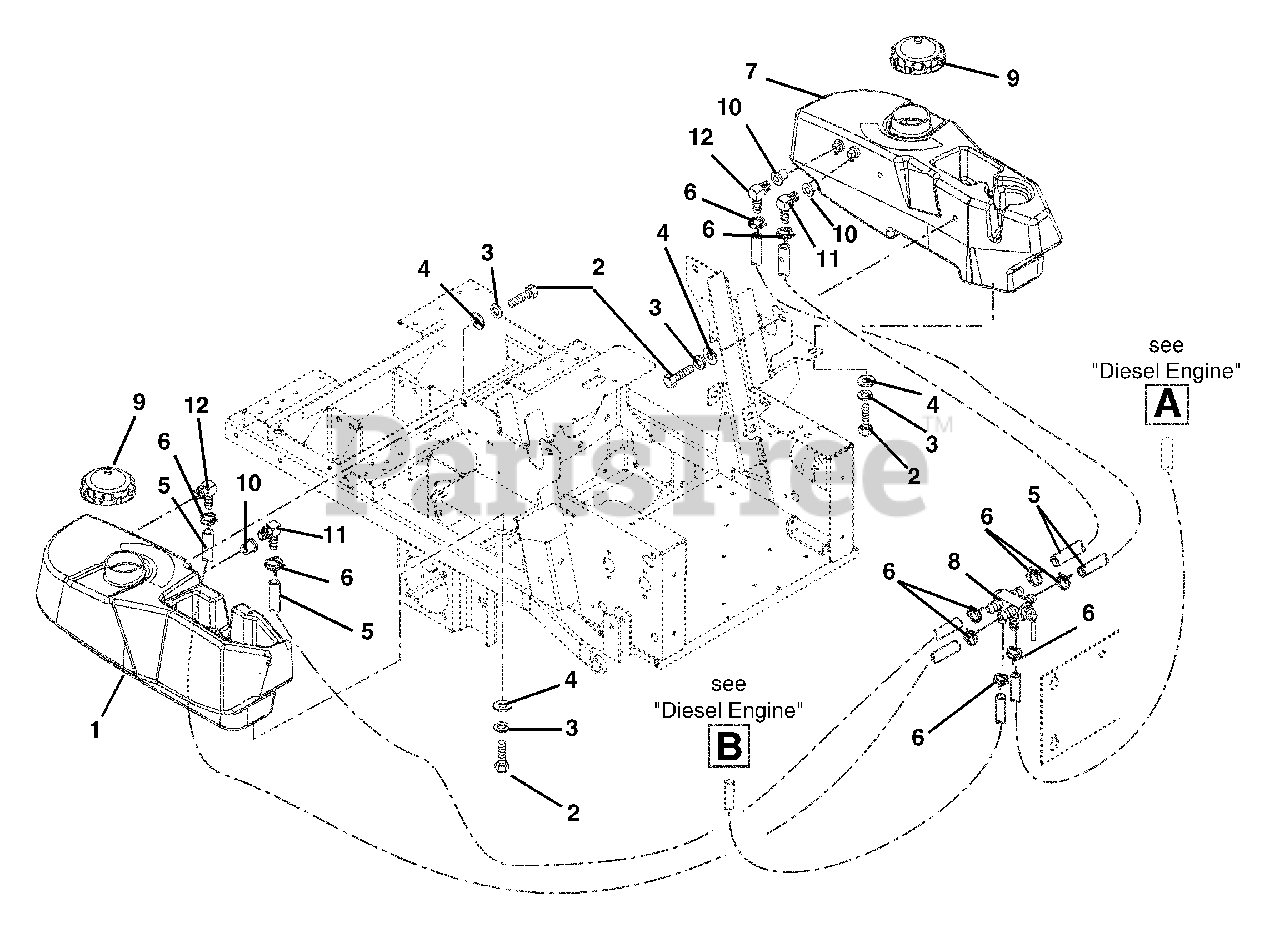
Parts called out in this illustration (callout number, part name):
1	Fuel Tank Right-Hand
2	Bolt-Hex .31-18 x .75 Grade 5
3	Washer-Locking .31 x .078
4	Washer-Flat-Steel .38 x .875 x .083
5	Hose, .31 ID
6	Hose-Clamp
7	Tank, Diesel Fuel- Left Hand
8	Valve, Fuel
9	Cap, Fuel
11	Fitting, Tank
12	Fitting, Tank
